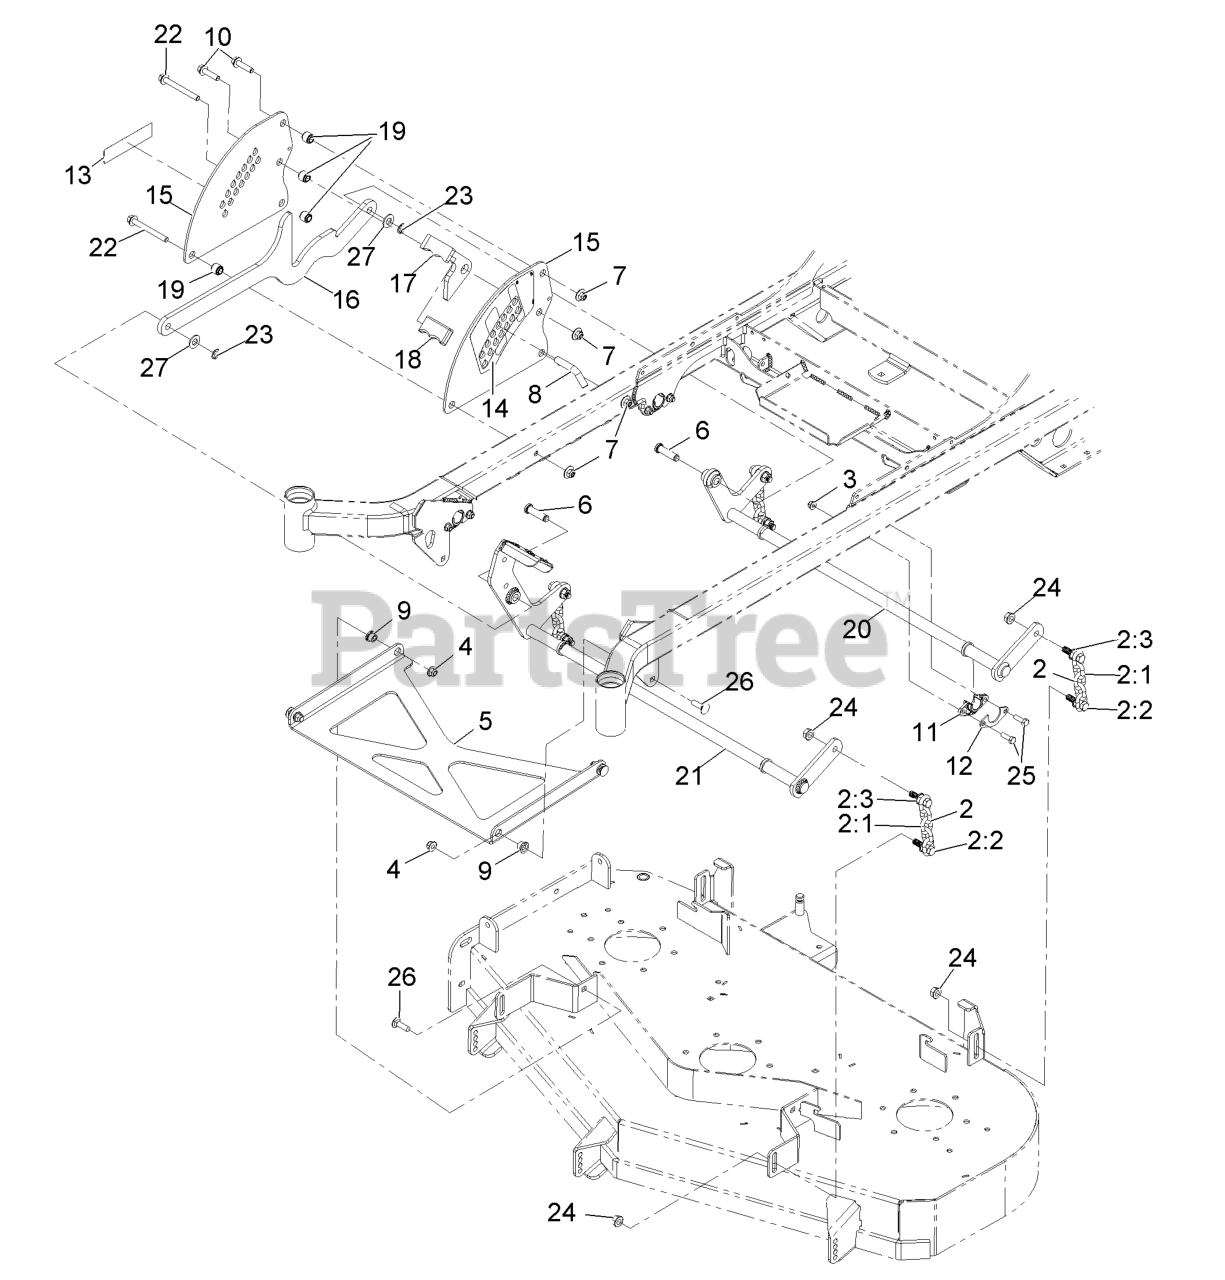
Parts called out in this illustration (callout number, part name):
2	DECK CHAIN ASM
2:1	CHAIN-LIFT, DECK
2:2	SCREW-HH
3	NUT-HF, NI
4	NUT-HF, NI
5	STRUT-DECK
6	PIN-CLEVIS
7	Nut-Nyloc 3/8-16 Flg
8	PIN-HOC
9	BUSHING-FLANGED
10	SCREW-HHF
11	BUSHING-FLANGE
12	GUSSET-LIFT, DECK
13	DECAL-E-SERIES
14	DECAL-HEIGHT OF CUT
15	PLATE,DECK LIFT
17	TRANSPORT LOCK-HOC
18	GRIP-FLAT
19	SPACER-STEP, DOUBLE
20	WLD,DECK LIFT SHAFT-REAR
21	WLD,DECK LIFT SHAFT-FRT
22	SCREW-HHF
23	RING-RETAINING, EXTERNAL
25	SCREW-HH
26	BOLT-CARR
27	WASHER-FLAT
